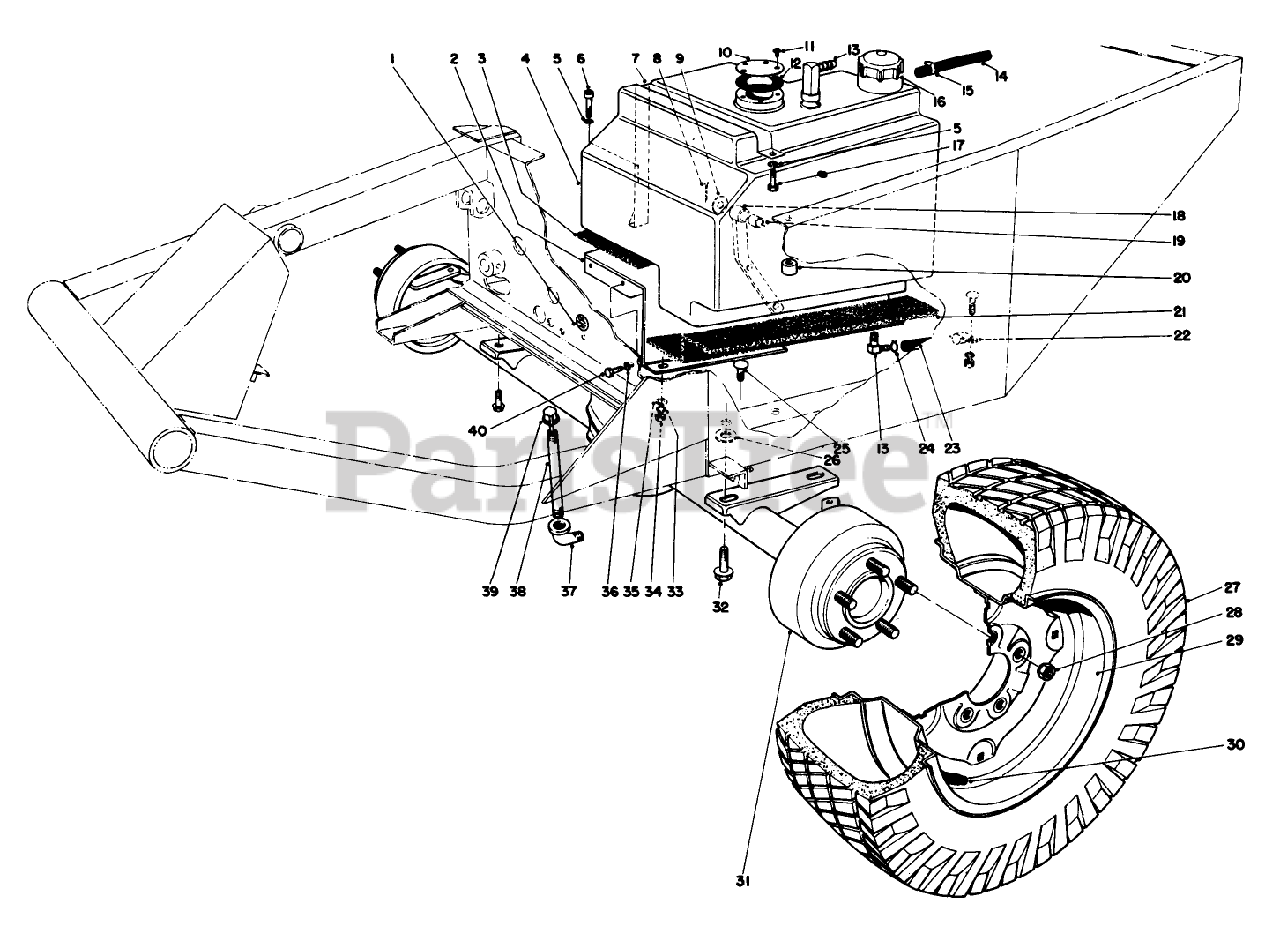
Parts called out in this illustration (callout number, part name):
1	OIL DECAL
2	GAS TANK BASE WA
3	FOAM-SUPPORT, TANK
4	Gas Tank (Incl. Ref. #13)
5	WASHER-LOCK
6	SCREW-HSH
7	STRAP-TANK, FUEL
8	PIN-COTTER
9	WASHER-THRUST
10	COVER FUEL TANK OPEN
11	SCREW-HWHTF
12	Gasket
13	FITTING-ELBOW, 90 DEG
14	HOSE-FUEL
15	CLAMP-HOSE
16	Gas Cap
17	SCREW-HH
18	Steering Link (Incl. Ref. #19)
19	BUSHING
20	SPACER
21	FOAM-SUPPORT, TANK
22	CLAMP-R
23	HOSE-FUEL
24	CLAMP-HOSE
25	BOLT-CARR
26	SHIM-AXLE
28	NUT-LUG
30	STEM-VALVE
31	AXLE WA RO
32	SCREW-HHF
33	WASHER-LOCK
34	NUT-HEX
35	WASHER-PLAIN
36	WASHER-LOCK
37	FITTING-ELBOW-90
38	NIPPLE-PIPE
39	DIPSTICK ASM
40	SCREW-HH, TAP
